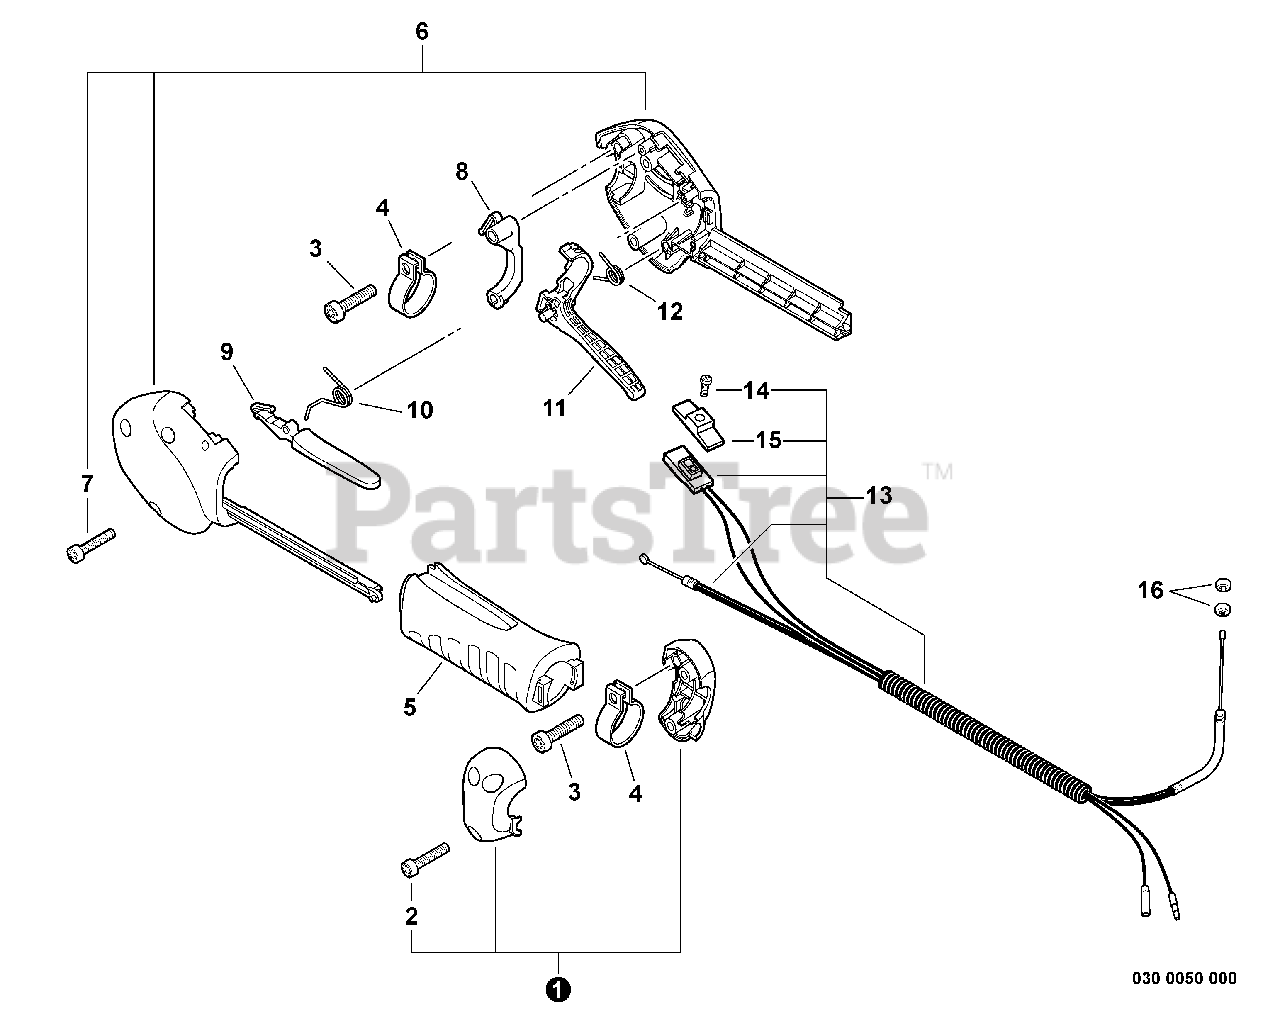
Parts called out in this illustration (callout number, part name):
1	FIXTURE SET, HANDLE
2	BOLT, TORX 4×20
3	BOLT, TORX 5×20
5	GRIP, HANDLE
6	HANDLE KIT, CONTROL
7	BOLT, TORX 4×20
8	LOCKOUT, THROTTLE
9	LEVER, THROTTLE LOCKOUT
10	SPRING, TORSION
11	TRIGGER, THROTTLE
12	SPRING, TORSION
13	CABLE ASSY, CONTROL
14	SCREW 3×10
15	KNOB, SWITCH - ORANGE
